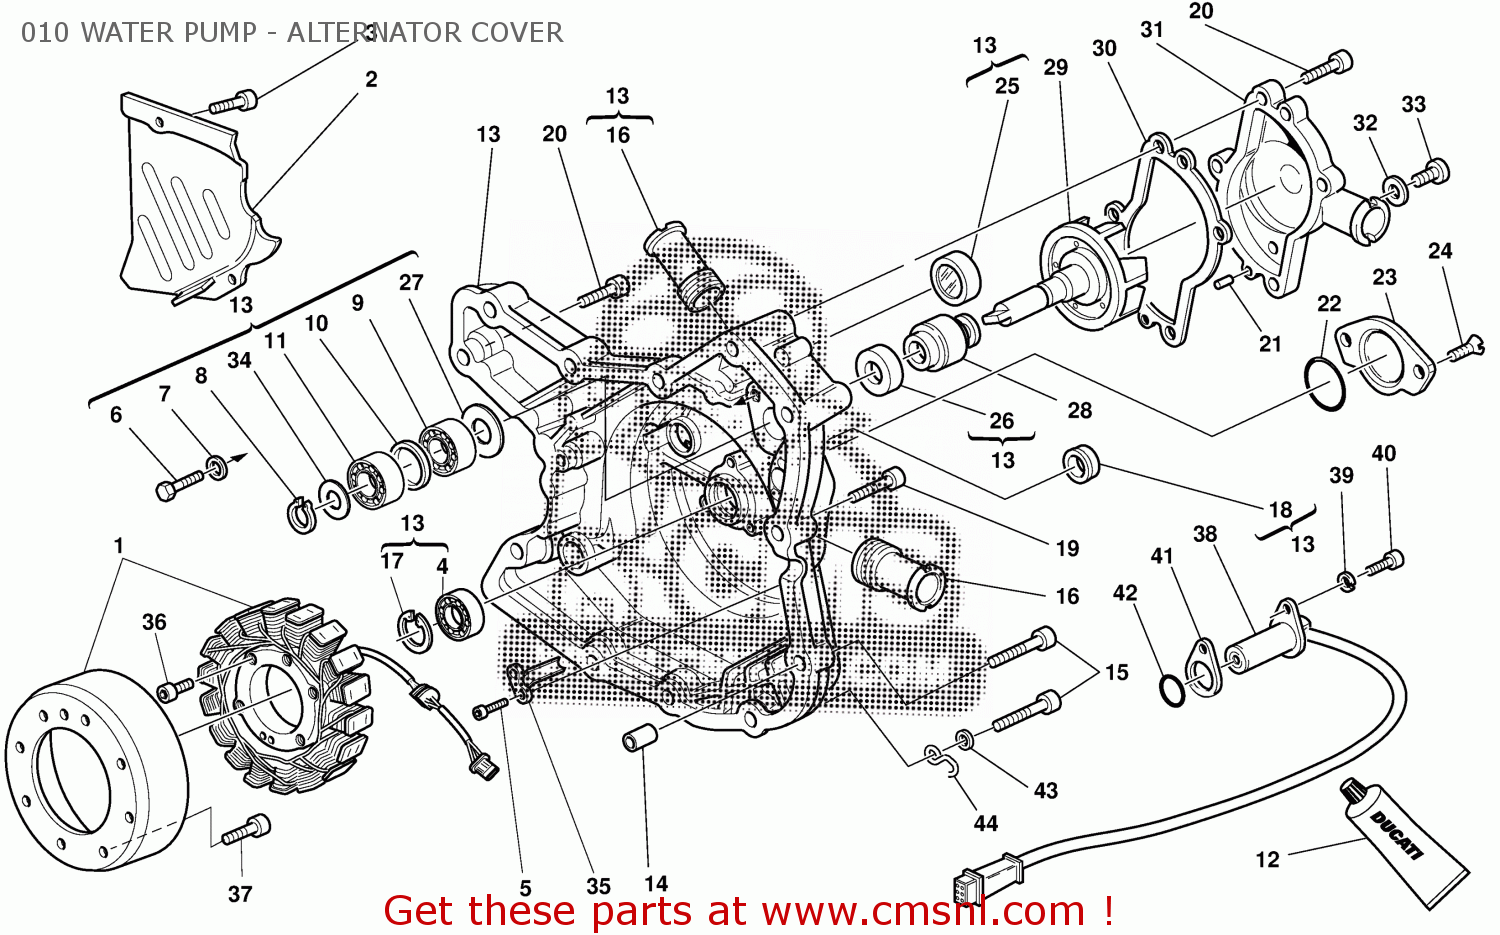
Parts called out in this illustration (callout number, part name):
1	GENERATOR
2	CHAIN PINION COVER
3	SCREW M5X12
4	BALL BEARING 6003 TN9 C3
5	SCREW M5X14
6	SCREW TE M6X1.00X16
7	WASHER
8	CIRCLIP
9	BALL BEARING 6000
10	SPACER
11	BALL BEARING 6000
12	LIQUID GASKET
13	GENERATOR COVER
14	PIN DOWEL
15	SCREW TCEI M6X1.00X30
16	WATER PUMP DELIVERY PIPE UNION
17	CIRCLIP
18	OIL SEAL
19	BOLT, SOCKET HEAD M6X25
20	SCREW
21	PIN DOWEL
22	O-RING
23	COVER
24	SCREW
25	LENS, IGNITION INSPECTION
26	MECHANICAL SEAL
27	SPACER
28	MECHANICAL SEAL
29	WATER PUMP ROTOR
30	GASKET HOUSING COVER
31	WATER PUMP COVER
32	COPPER GASKET 11.9X8.2X2
33	PLUG
34	WASHER 10X17X1.8
35	BRACKET
36	SCREW M6X40
37	SCREW
38	SENSOR, TIMING & RPM
39	WASHER, SPRING
40	SCREW TCEI M6X1.00X16
41	GASKET 0.6 MM
42	O-RING
43	WASHER
44	RING
